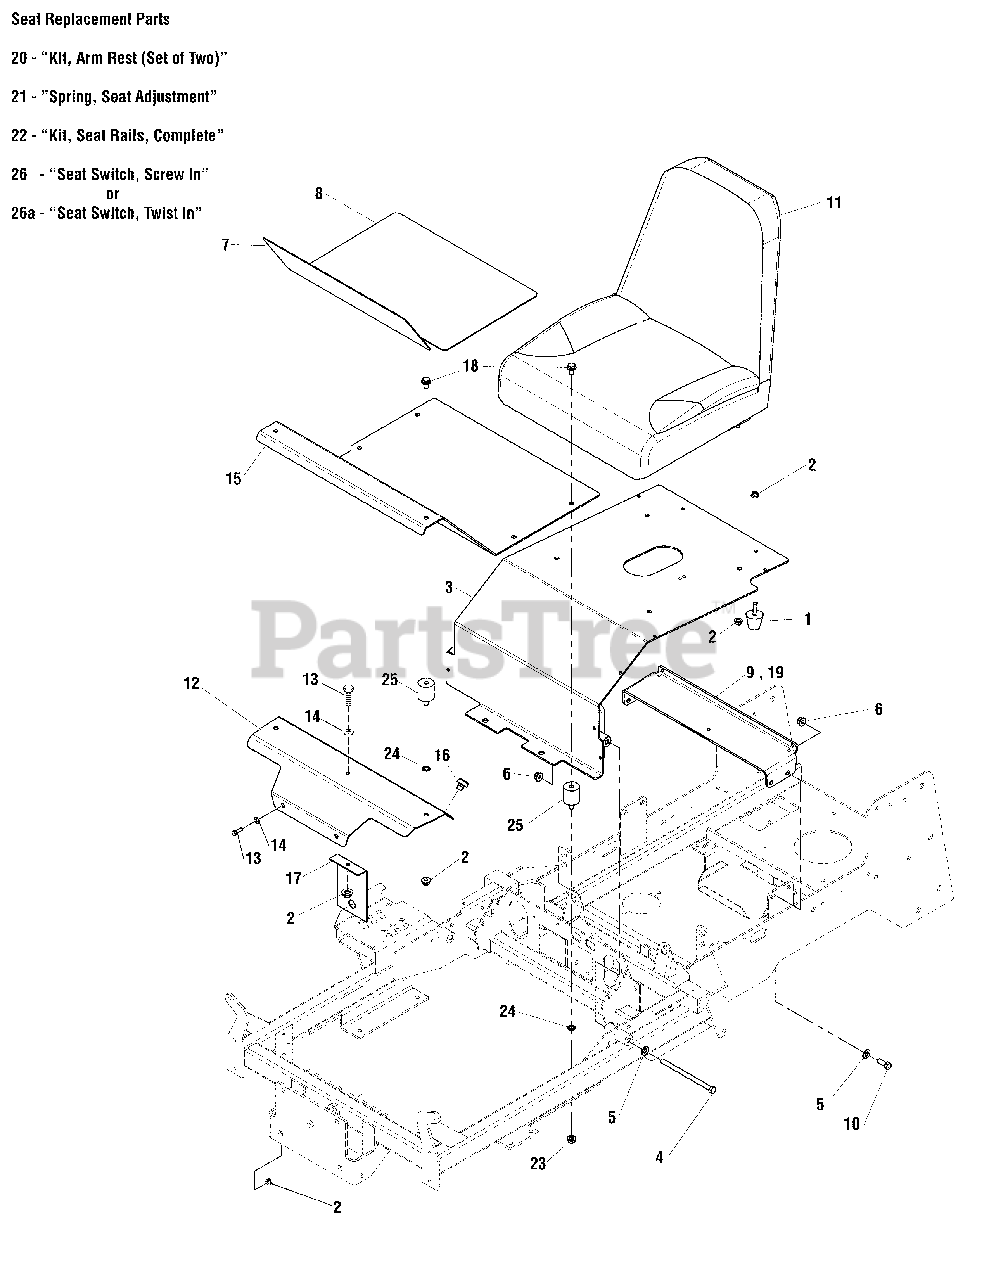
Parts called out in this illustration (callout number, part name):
1	BUMPER, RUBBER 5/16-18
2	NUT, 5/16-18 HEX NYLOCK FLANGE
3	WELD, SEAT PLATE - RED
4	BOLT, 3/8-16 X 6" GD5 YZ
5	WASHER, 3/8" SAE
6	NUT, 3/8-16 HEX NYLOCK FLANGE
7	SAFETY WALK, 17.17 X 6.00
8	SAFETY WALK, 17.13 X 11.50
9	WELD, SEAT SUPPORT - ORG
10	BOLT, 3/8-16 X 1" GD5 YZ
11	SEAT, NO ARM REST
12	PLATE, FLOOR PAN, FRONT - IS500Z
13	BOLT, 5/16-18 X 1" GD5 YZ
14	WASHER, 5/16" GD.9 FLAT
15	PLATE, FLOOR PAN, REAR - IS500Z
16	MNT, VBRTN
17	PLATE, SUPPORT, FRONT FLOOR
18	BOLT, 5/16-18 X 5/8, FLANGE SERRATED
19	PLATE, SEAT SUPPORT, ZT4000 - ORG
20	KIT, ARM REST (SET OF TWO)(SV)
21	SPRING, EXTENSION, SEAT ADJUSTMENT (BLK OR SLVR)
22	KIT, SEAT RAILS (COMPLETE)(SV)
23	NUT, 5/16-18 HEX NYLOCK FLANGE SMALL
24	WASHER, 3/8" INT TOOTH LOCK
25	MTN, VBRTN, 30 DURO
26	SWITCH, MILSCO SEAT, 2 SCREW
